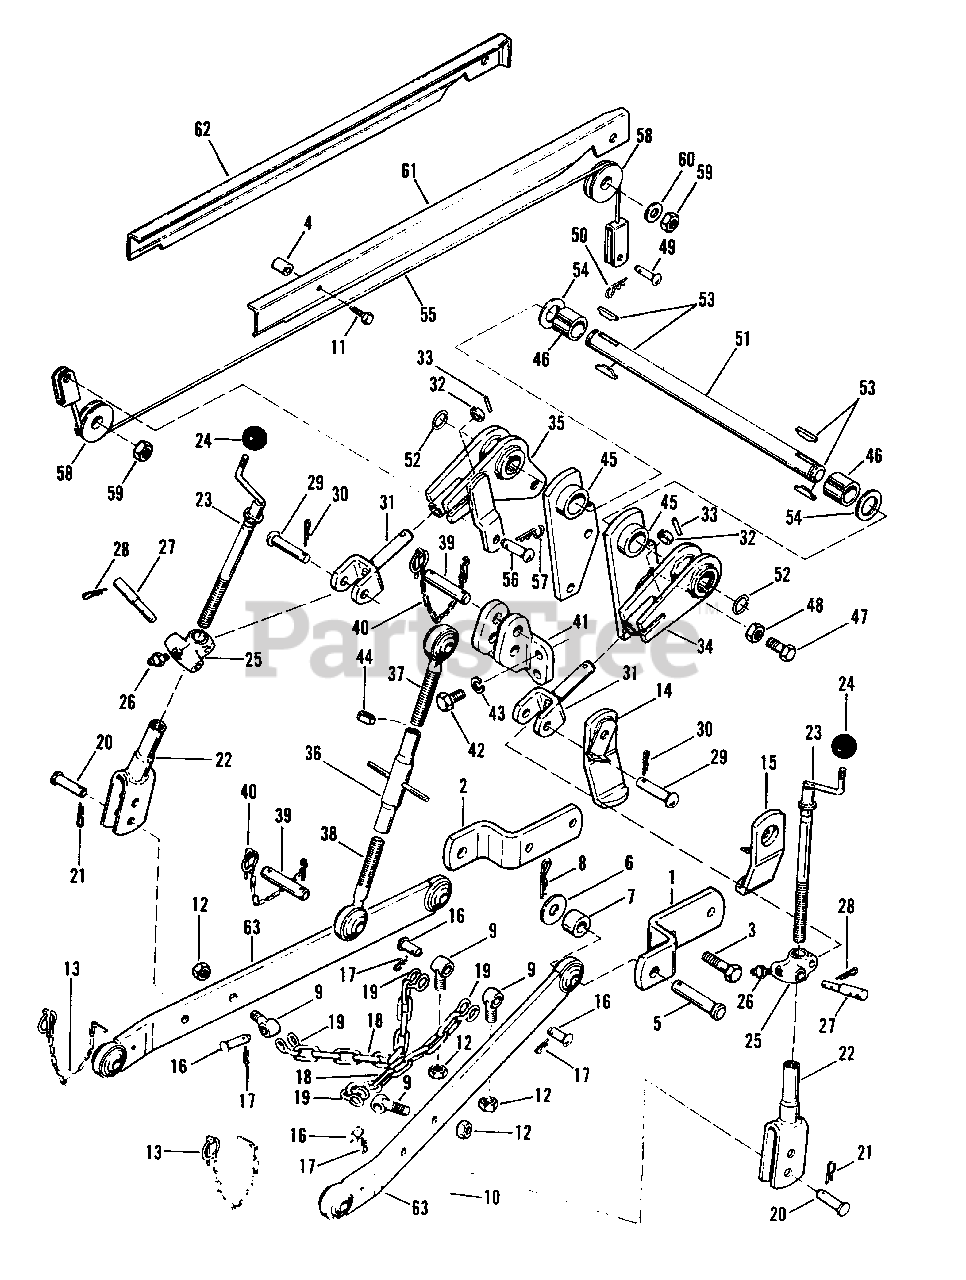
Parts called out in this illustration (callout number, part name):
1	Pull Link Strap, R.H.
2	Pull Link Strap, L.H.
3	Hex Capscrew, 1/2"-13 x 2" lg.
8	Hair Pin Clip
10	Cotter Pin, 1/4" x 1-1/2" lg.
11	Self Tapping Screw 1/4"-20 x 1-1/4" lg.
12	Hex Nut, Lock, 1/2"-20
13	Retaining Ring
14	Rub Bar Assy. L.H.
15	Rub Bar Assy. R.H.
16	Pin
17	Spring Clip
21	Hair Pin Clip
22	Clevis Assembly
23	Link Assembly
26	Grease Fitting
28	Hair Pin Clip
30	Hair Pin Clip
31	Clevis Assembly
34	Lift Arm Assy. R.H.
35	Lift Arm Assy. L.H.
36	Upper Link Assy.
37	Stud Assembly, R.H.
38	Stud Assembly, L.H.
40	Retaining Ring
41	Upper Support Link
42	Hex Capscrew, 7/16"-14 x 1-1/4" lg.
43	Lock Washer, 7/16"
44	Hex Nut, Full
45	Support Assembly
47	Hex Capscrew, 1/2"-13 x 1-1/2" lg.
50	Hair Pin Clip
51	Rock Shaft
52	Retaining Ring
55	Cable Assembly
57	Spring Clip
59	Hex Nut, Lock, 1/2"-13
60	Plain Washer, 7/16"
61	Wire Guard, R.H.
62	Wire Guard, L.H.
63	Pull Link Assembly
